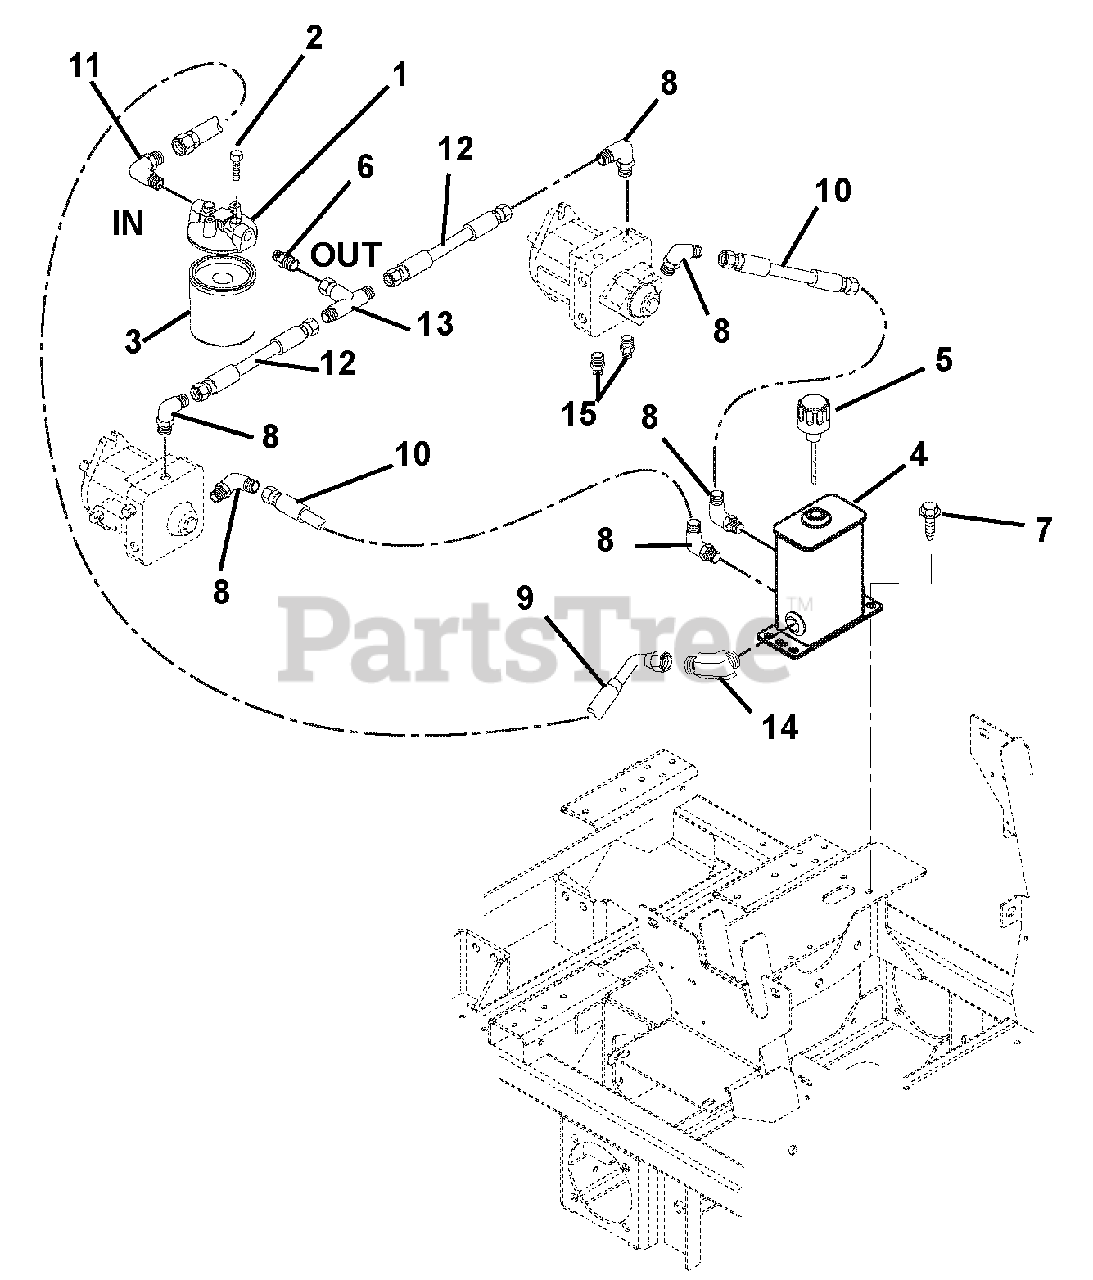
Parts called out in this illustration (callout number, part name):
1	Head, Filter
2	Bolt, Hex .25-20 x .50 Grade 5 Epoxy
3	Oil Filter w/ Bypass
4	Body, Hydraulic Tank
5	Breather, Dipstick
6	Fitting, Hydraulic, Straight
7	Screw, Tapping .38-16 x .75 Hex Washer Head
8	Fitting, Hydraulic, 90 Degree Elbow
9	Hose, Hydraulic Valve to Tank
10	Hose, Hydraulic, 10-inch
11	Fitting, Hydraulic, 90 Degree Elbow
12	Hose, Hydraulic .50, 5-Inch
13	Fitting, Hydraulic Tee
14	Fitting, Hydraulic 45 Degree M8F-M80
15	Fitting, Hydraulic (4 F5OLO)
